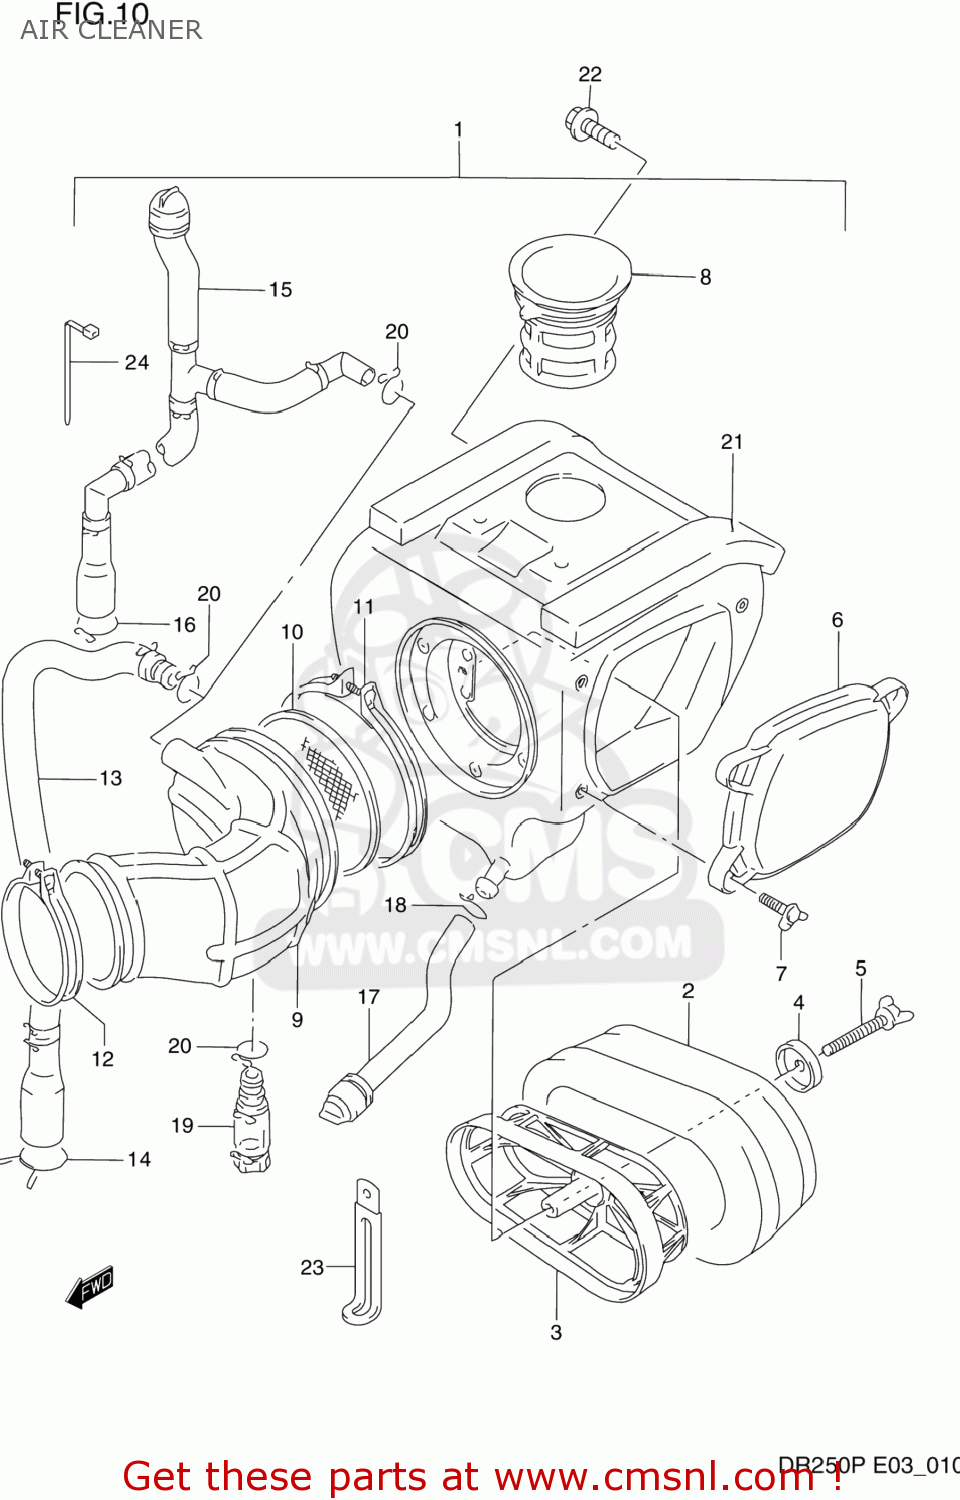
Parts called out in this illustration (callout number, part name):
1	CLEANER ASSEMBLY,AIR
2	FILTER
3	HOLDER,FILTER
4	WASHER,AIR CLEANER
5	BOLT,WING
6	CAP,AIR CLEANER
7	BOLT,WING
8	TUBE,INLET
9	TUBE,OUTLET
10	TRAP,FRAME
11	CLAMP
12	CLAMP
13	TUBE,BREATHER
14	CLIP
15	TUBE,BREATHER
16	CLIP
17	DRAIN TUBE
18	CLIP
19	TUBE,DRAIN B
20	CLIP
21	CUSHION
22	BOLT
23	CLAMP
24	CLAMP(L:165)
